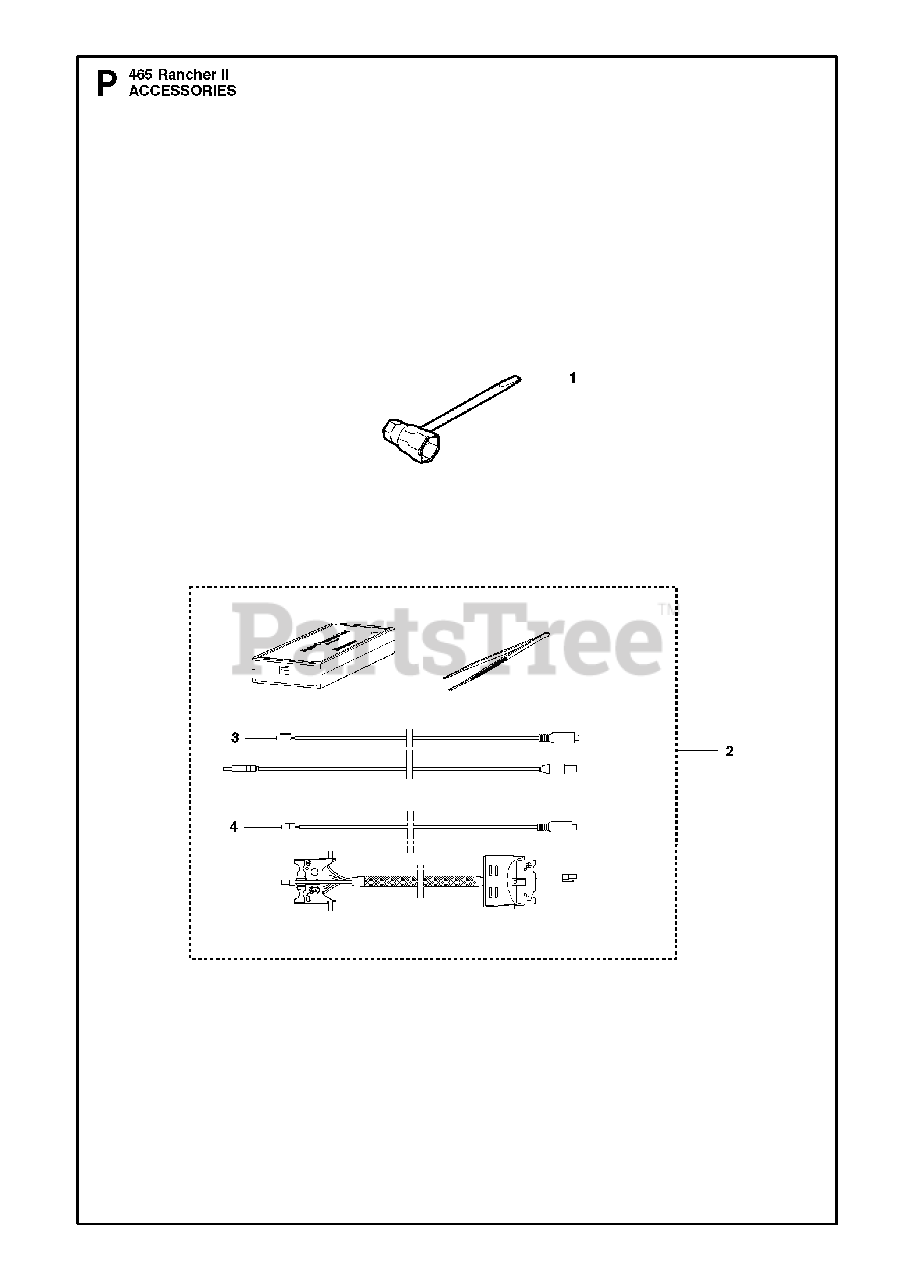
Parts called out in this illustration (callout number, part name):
1	COMBI TOOL
2	DIAGNOSTIC TOOL KIT
3	CABLE ASSY
4	CABLE ASSY
